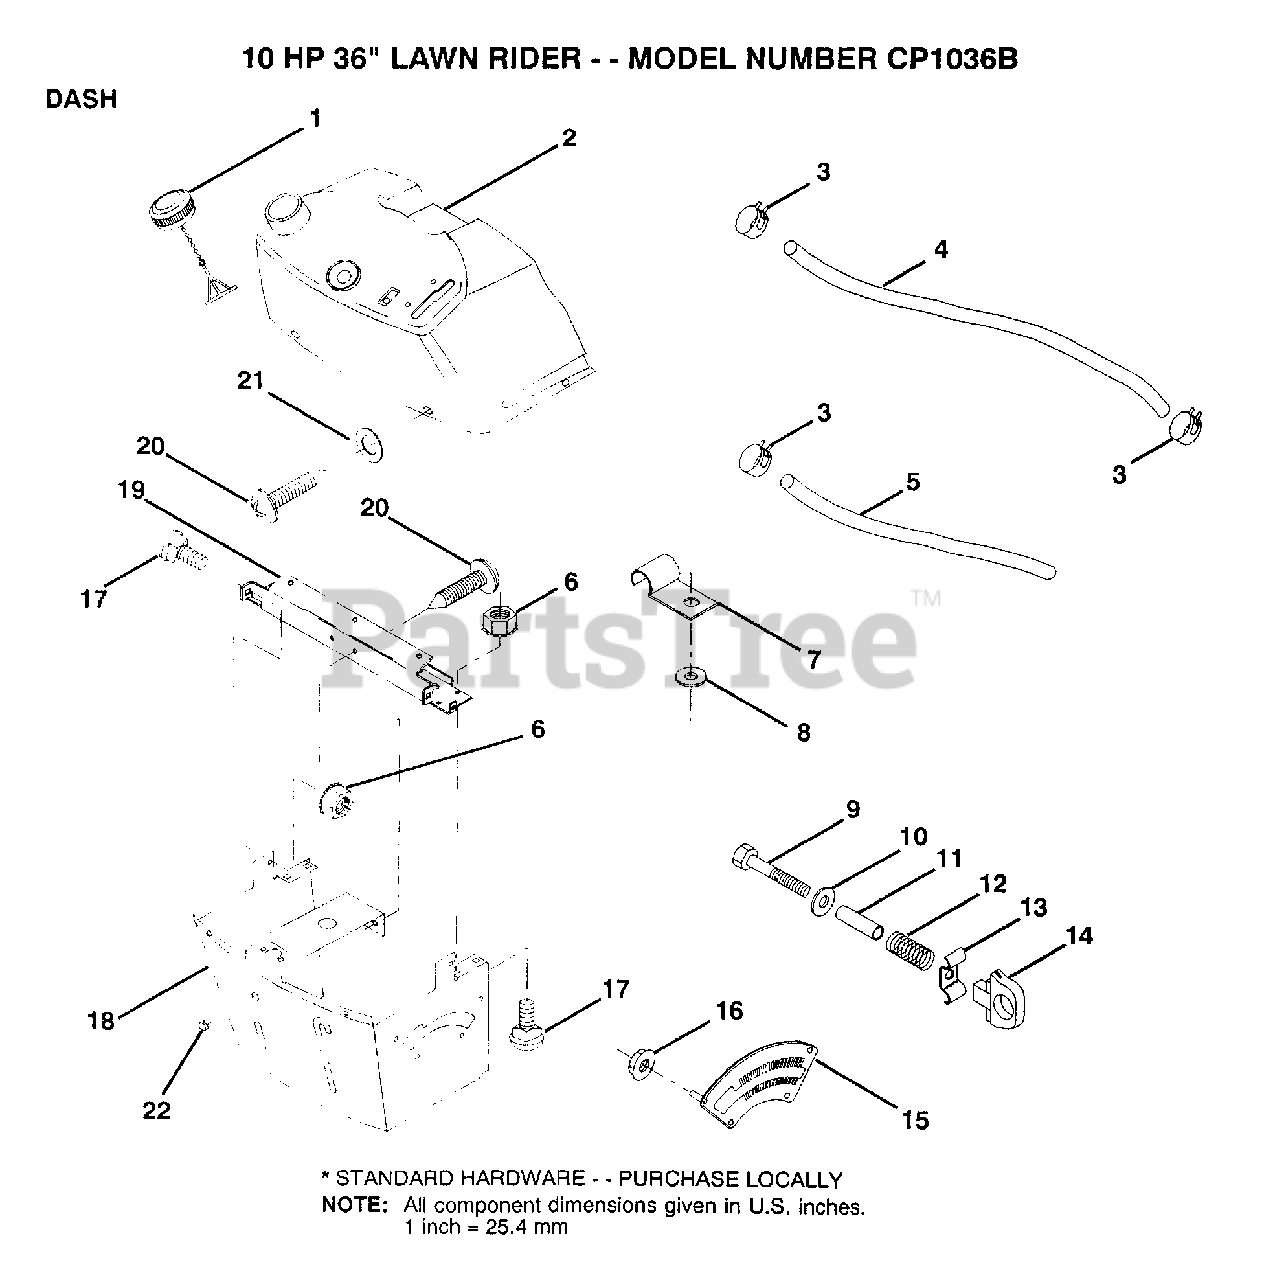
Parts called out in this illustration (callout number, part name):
3	HOSE CLAMP
5	FUEL LINE T
6	NUT
7	CLIP T
8	WASHER PM
9	BOLT
10	WASHER PM
11	SPACER SPLIT
12	SPRING M
13	"KNOB,HGT RETAINER"
14	KNOB
15	ADJUSTER QUAD
16	NUT
17	BOLT
18	SUPT ASSY DASH
19	CROSS BRACE
22	PLUG DOME
